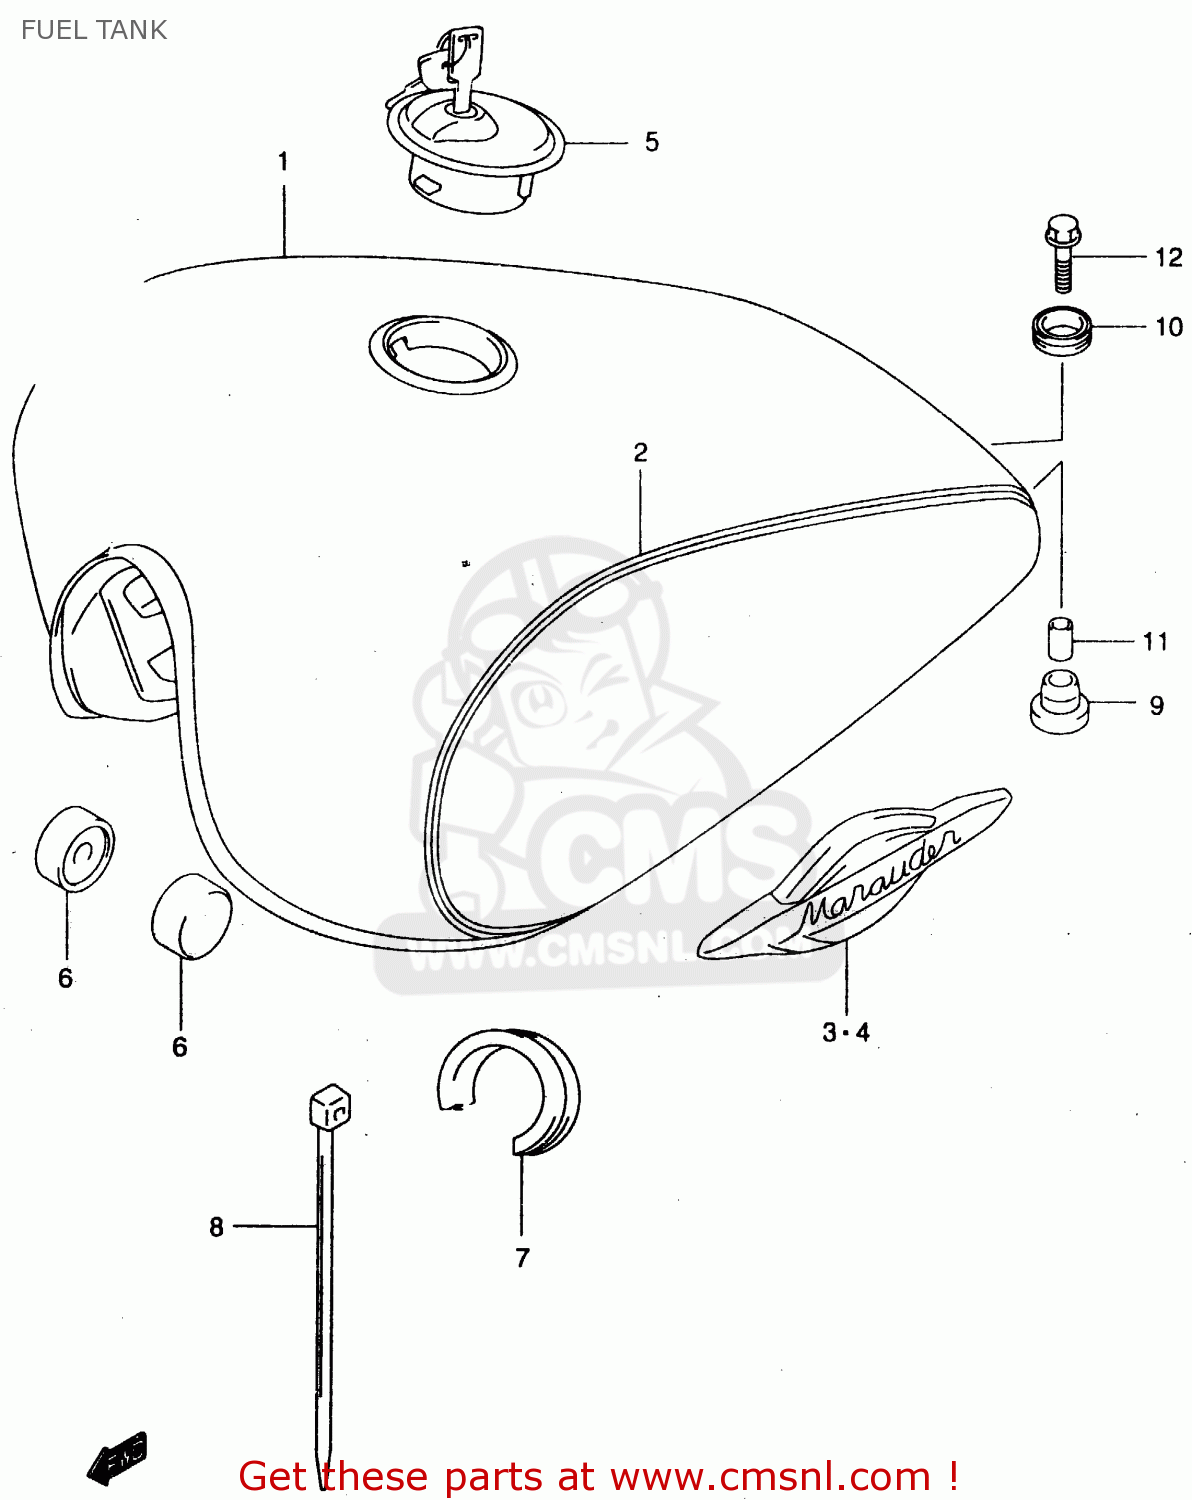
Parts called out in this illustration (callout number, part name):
1	TANK ASSEMBLY,FUEL
2	TAPE SET,FUEL TANK
3	EMBLEM,FUEL TANK,RIGHT
4	EMBLEM,FUEL TANK,LEFT
5	CAP SET,FUEL TANK
6	CUSHION
7	CUSHION,FUEL TANK SIDE
8	CLAMP(L:250)
9	CUSHION
10	CUSHION,FUEL TANK RR
11	SPACER(6.5X9X18)
12	BOLT
